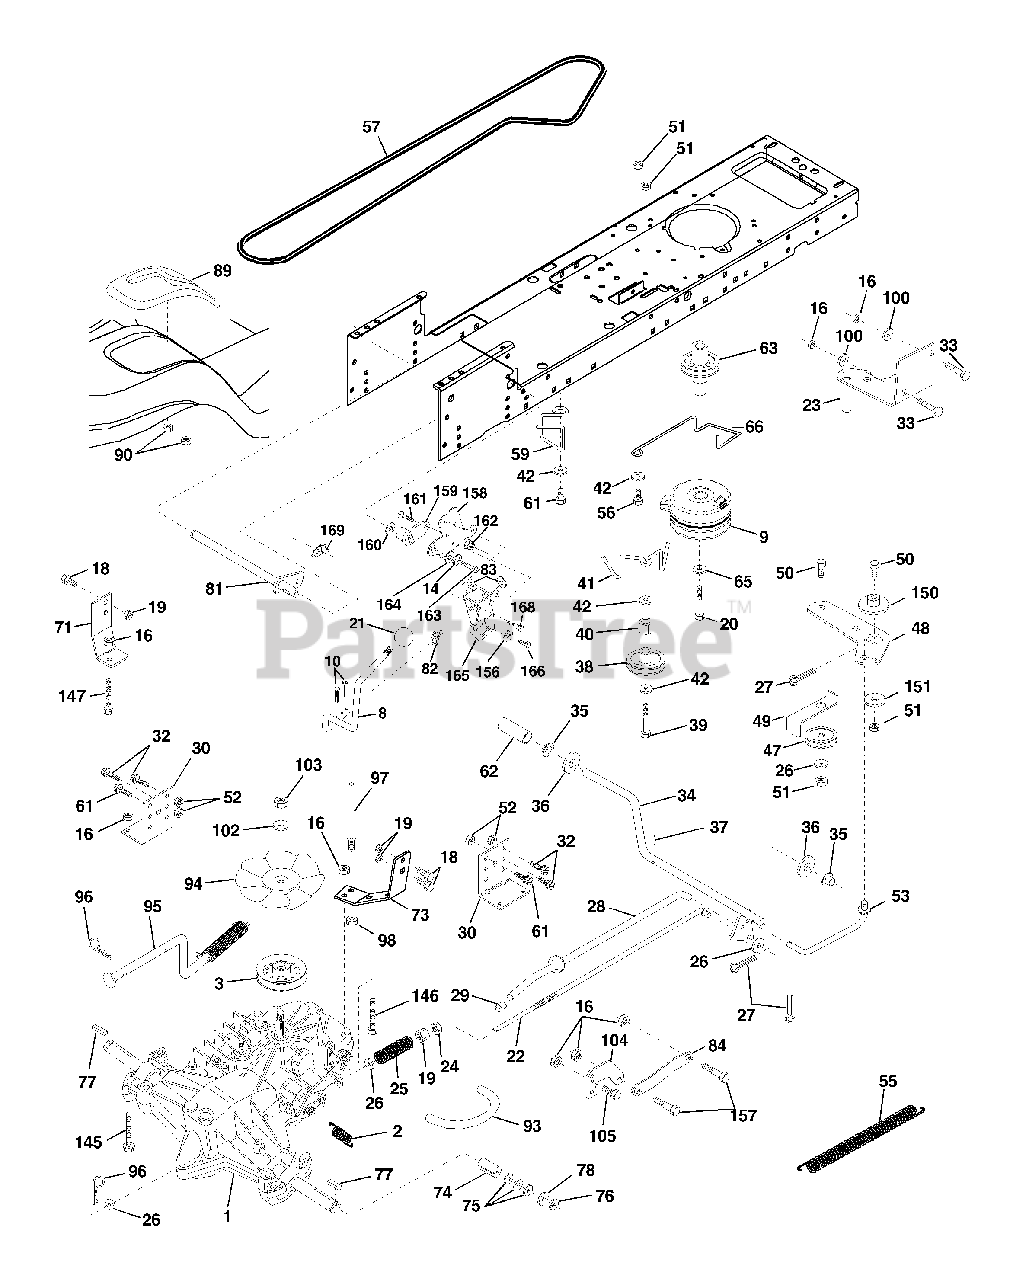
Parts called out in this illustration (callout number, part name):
1	Transaxle
2	Spring, Return, Brake
3	Pulley, Transaxle
8	Rod Shift Fender Adjust STLT
9	Clutch, Elect. EVX LT Mag 5217-2
10	Pin Cotter 1/8 x 1 CAD
14	Washer Lock Hvy Helical
16	Nut Lock Hex W/Ins. 5/16-18 Unc P
18	Bolt Fin Hex 3/8-16 Unc x 1 Gr. 5
19	Nut Lock Hex W/Wsh 3/8-16 Unc
20	Bolt Hex 7/16-20 x 4-1/4 Ga. 1.38
21	Knob, Duckhead 1/2-13
22	Rod, Brake Hydro
23	Bracket, Asm Clutch Mtg EVX
24	Nut
25	Spring, Brake Rod
26	Washer
27	Pin Cotter 1/8 x 3/4 CAD.
28	Rod, Parking Brake
29	Cap, Parking Brake
30	Bracket, Transaxle
32	Bolt Hex Hd 5/16-18 Unc x 3/4
33	Bolt Rdhd Sqnk 5/16-18 UNC x 3/4
34	Shaft, Foot Pedal
35	Bearing, Nylon
37	Pin, Roll
38	Pulley, Idler, Flat
40	Spacer, Split
41	Keeper, Belt Idler
42	Washer 13/32 x 13/16 x 12 Gauge
47	Pulley, Idler, V-Groove
48	Bellcrank Clutch Grnd Drv Stl
49	Retainer, Belt
50	Bolt
52	Nut Crownlock 5/16-18
53	Link, Clutch
55	Spring, Return, Clutch
56	Bolt Fin Hex 3/8-16 UNC x 1-1/4
57	V-Belt, Ground Drive
59	Keeper, Center Span
61	Screw Thdrol. 3/8-16 x 3/4 Ty. TT
62	Cover, Pedal
63	Pulley, Clutch Electric EVX
65	Washer
66	Keeper Belt Engine Hydro
71	Strap Torque Lh Hydro
73	Strap Torque Rh Hydro
74	Spacer, Split
75	Washer 25/32 x 1-1/4 x 16 Gauge
77	Key, Square
78	Washer 25/32 x 1-5/8 x 16 Gauge
81	Shaft Asm Cross Tapered 500 18"
82	Spring Torsion
83	Washer 17/32 x 3/4 x 16 Ga.
84	Link Transaxle Hydr 0500
89	Console, Shift
90	Nut, Self-Thd Wsh-hd 1/4 Zinc
93	Line Fuel Hydro 4"
94	Fan, Hydro 7"
95	Control Asm Bypass Hydro
96	Retainer Spring 1" Zinc/Cad
97	Keeper Belt Rh Hydro
98	Nut Keps Hex 3/8-16 Unc
100	Washer 11/32 x 3/4 x 16 Ga.
103	Nut Nylon Insert 1/2-20 Unf.
104	Arm, Control Hydro
105	Screw Cap Hex 5/16 x 18 x 1
108	Screw Hex Wh Hd #10-24 x
109	Adaptor Fan Hydro LT Hyd Alum
145	Bolt, Hex Flghd 5/16-18 Gr. 5
146	Bolt Hex Flghd 5/16-18 x 2-1/4
147	Bolt Hex Flghd 5/16-18 x 1-1/2
150	Bushing Bellcrank Grd Drive
151	Washer 13/32 x 2 x 10 Ga.
156	Washer Srrted 5/16ID x 1.125
157	Bolt Shoulder 5/16-18 Unc - 2A
158	Bracket Shift Mount
159	Hub Tapered Flange Shift Lt
160	Washer 29/32 x 1/4 x 16 Ga
161	Bolt Rdhd Sqnk 1/4-20 Unc
162	Nut Crownlock 1/4-20 Unc
163	Bolt Hex Fin 1/4-20 Unc x 1 Gr 5
164	Washer 5/8 x 0281 x 10 Ga
165	Bracket Pivot Lever
166	Screw 5/16-18 x 5/8
168	Bolt Shoulder 5/16-18 x .561
169	Plate Fastening Cross Sh STLT/CRD
